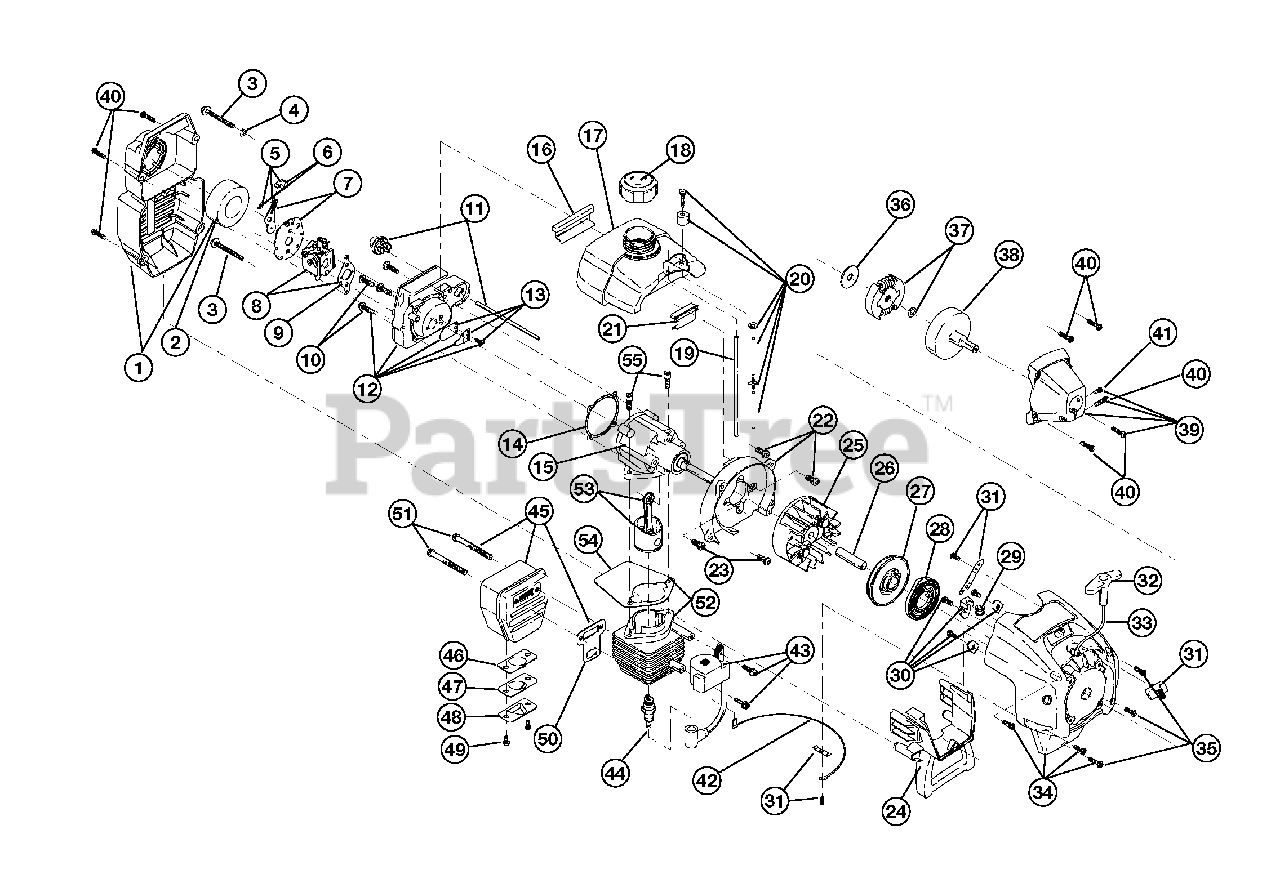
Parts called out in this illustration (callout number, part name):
1	Air Cleaner/Muffler Cover Assembly
2	Air Cleaner Filter
3	Carburetor Mounting Screw Assembly
4	Wavey Washer
5	Choke Lever Assembly
6	Choke Knob and Screw
7	Choke Lever and Plate
8	Carburetor Assembly
9	Carburetor Gasket
10	Carb Mount Screw
11	Primer and Hose Assembly
12	Carb Mount Assembly
13	Reed Assembly
14	Carburetor Mount Gasket
15	Crank Case Service Assembly
16	Rear Mounting Pad
17	Fuel Tank Assembly
18	Fuel Cap Assembly
19	Fuel Return Line
20	Fuel Line Assembly
21	Front Mounting Pad
22	Shroud Assembly
23	Shroud Screw
24	Shroud Extension and Stand
25	Flywheel Assembly
27	Recoil Pulley Assembly
28	Recoil Spring
29	Rope Guide
30	Pulley Retainer Assembly
31	Switch Assembly
32	Pull Handle
34	Starter Housing Assembly
35	Housing Screw
36	Clutch Washer
37	Clutch Rotor Assembly
38	Clutch Drum Assembly
39	Clutch Cover Assembly
40	Cover Screw
41	Anti-Rotation Screw
42	Wire Lead
43	Module Assembly
44	Spark Plug
45	Muffler Assembly
46	Spark Arrestor Screen
47	Spark Arrestor Plate
48	Spark Arrestor Hood
49	Spark Arrestor Screw
50	Exhaust Gasket
51	Muffler Mounting Bolt Assembly
52	Cylinder Assembly
53	Piston and Rod Assembly
54	Cylinder Gasket
55	Cylinder Bolt
